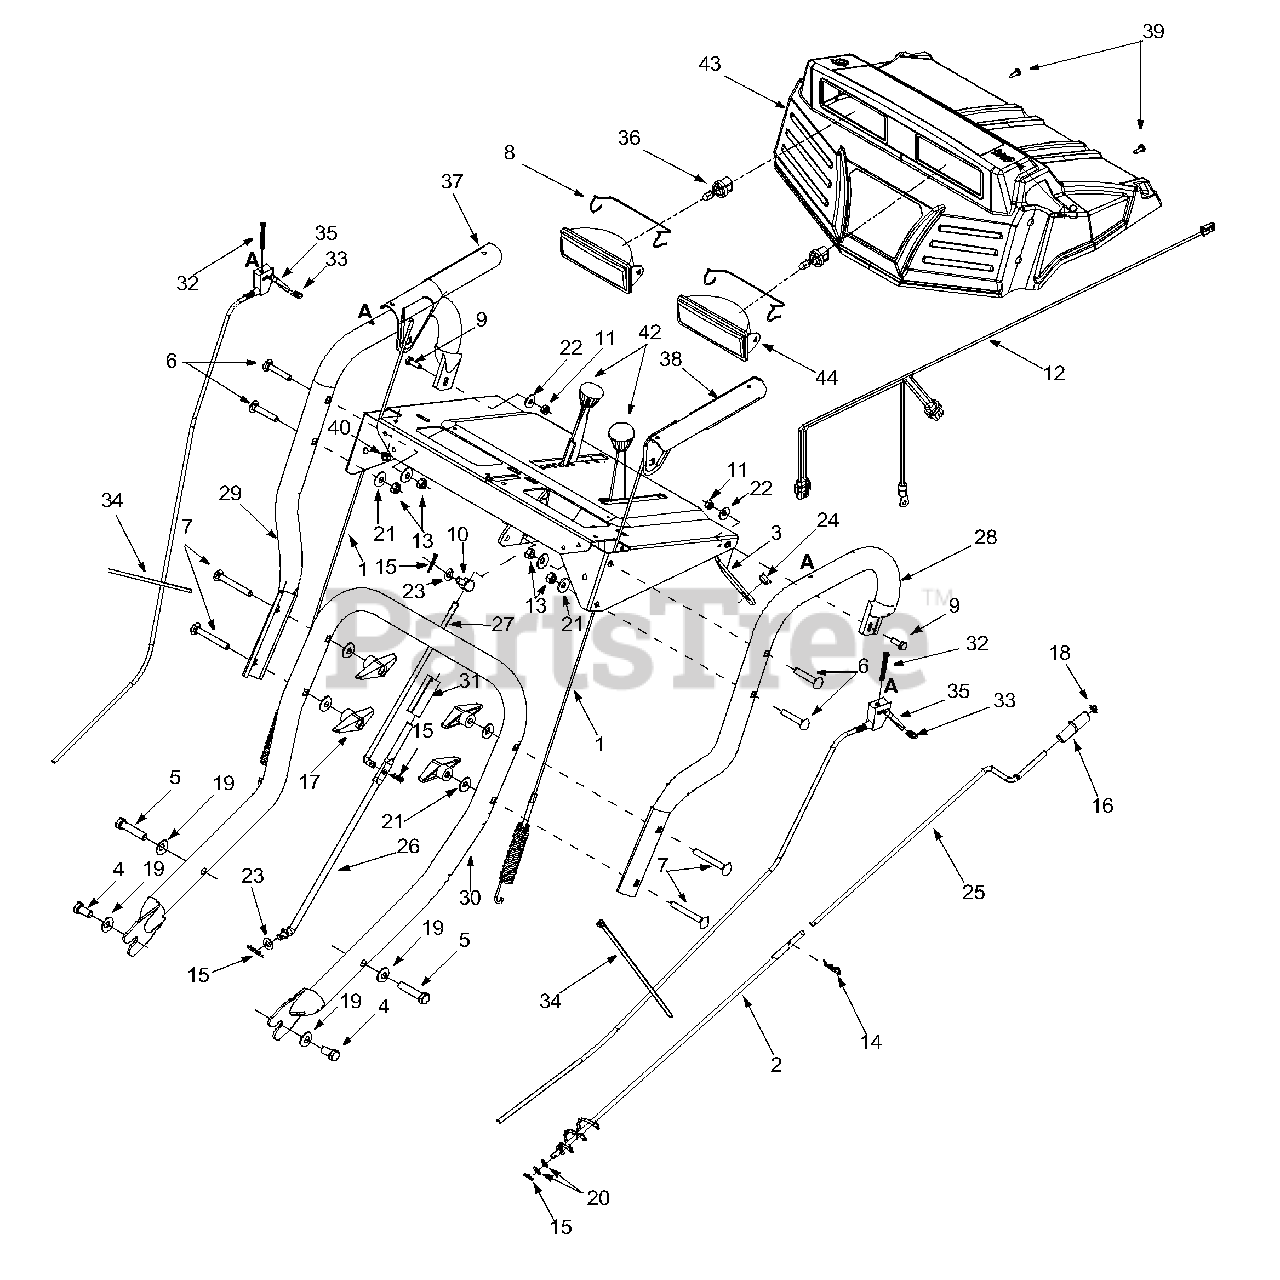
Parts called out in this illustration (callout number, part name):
1	Cable Assembly: Auger/Drive
4	Hex Screw, 3/8-16 x .88"
5	Hex Screw, 3/8-16 x 1.75"
6	Carriage Bolt 5/16-18 x 1.75"
7	Carriage Bolt 5/16-18 x 2.5"
8	Lamp Retainer
9	Hex Screw 1/4-20 x .75"
10	Ferrule
11	Hex Nut 1/4-20
12	Lamp Wire Harness
14	Hairpin Clip
15	Hairpin Clip
16	Chute Crank Knob
19	Bell Washer
20	Flat Washer
21	Beleville Washer
22	Bell Washer
23	Flat Washer
24	Plastic Bushing
26	Lower Shift Rod
27	Upper Shift Rod
31	Clutch Rod Connector
32	Oval C-Sunk Screw
33	Flat Weld Nut
34	Cable Tie
35	Trigger Control
36	Halogen Lamp
37	Handle Engagement RH
38	Handle Engagement LH
39	Special B Screw
40	Hex Sems Nut
42	Shift Knob
43	Handle Panel
44	Lens Assembly
